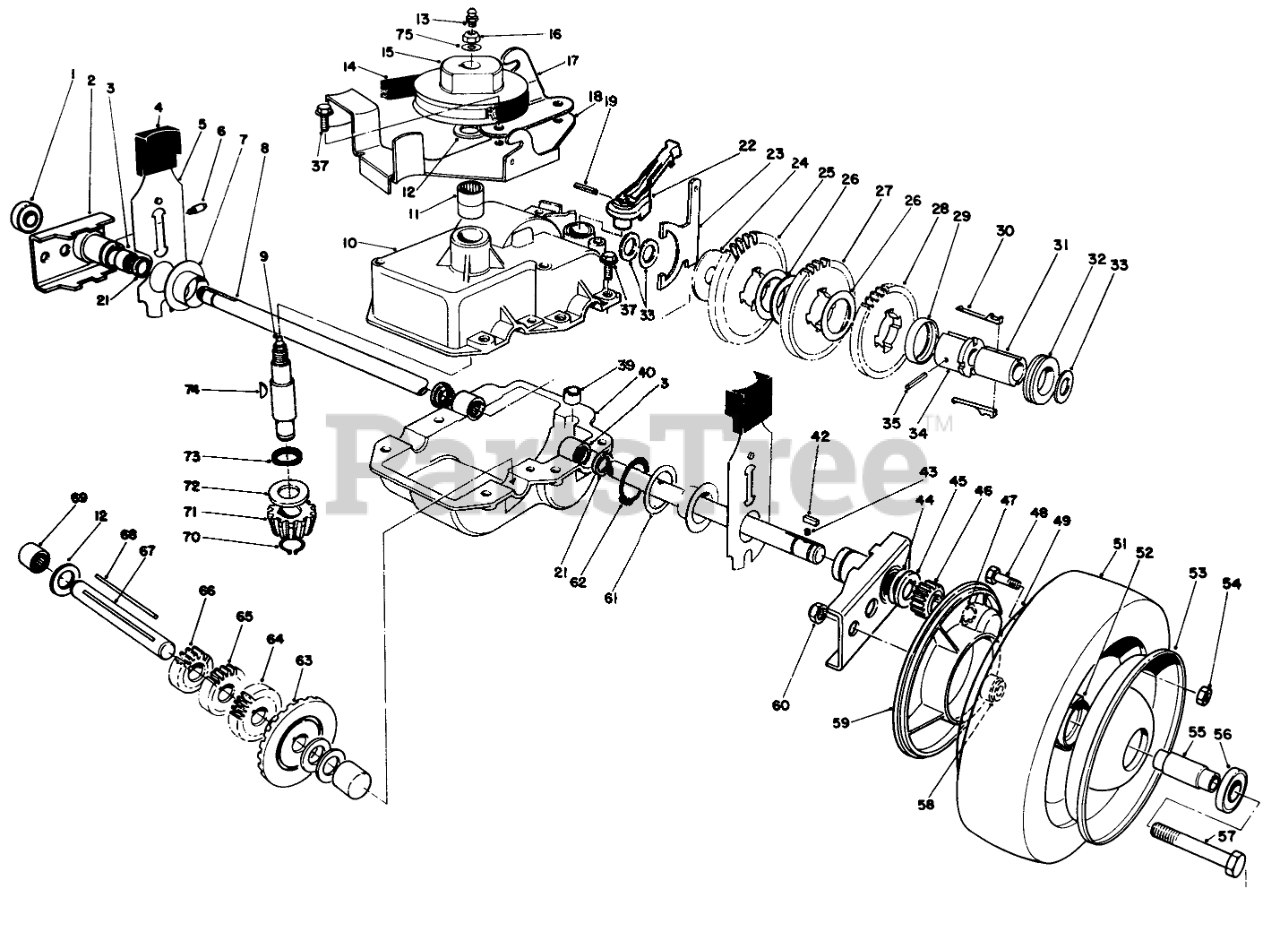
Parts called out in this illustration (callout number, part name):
1	BEARING-WHEEL
2	Pivot Arm Assembly (Incl. Ref. #1, 3, 6 & 21)
3	BEARING-ROLLER
4	KNOB-ARM
5	REAR SPRING ARM ASM
6	FITTING-GREASE
7	CAP-END
8	SHAFT-OUTPUT
9	Shaft-Input (Incl Ref. #13)
10	Upper Case Assembly (Incl. Ref. #11 & 73)
11	Bearing-Needle
12	WASHER-THRUST
13	FITTING-GREASE, ZERK
14	V-BELT
15	PULLEY
16	NUT-HEX
17	Bracket-Traction Engage
18	Belt Guide Bracket
19	PIN-COIL
21	SEAL-OIL
22	LEVER-SHIFT
23	YOKE-SHIFT
24	WASHER
26	WASHER
27	GEAR-42T
28	GEAR-38T
29	RETAINER-KEY
30	KEY-SHIFT
31	SLEEVE
32	COLLAR-SHIFT
33	WASHER-PLAIN
34	SLEEVE-GEAR
35	PIN-GROOVE
37	SCREW-HWHTF
39	BUSHING-YOKE
40	CASE-GEAR, LOWER
42	KEY RECTANGULAR
43	SPRING-COMPRESSION
44	WASHER-THRUST, OUTER
45	WASHER-THRUST, OUTER
46	GEAR-PINION
47	RING-RETAINING
48	SCREW-HH
49	Wheel-Half
52	HUB-BEARING
53	Wheel-Half
54	NUT-LOCK, NI
55	SPACER-BEARING
56	BEARING-WHEEL
57	SCREW-HH
58	SPACER-COVER, WHEEL
59	COVER-WHEEL
60	NUT-LOCK, CONE
61	WASHER
62	RING-RETAINING
63	GEAR-BEVEL
64	GEAR-18T
65	GEAR-14T
66	GEAR-12T
67	SHAFT-INTERMEDIATE
69	BEARING-NEEDLE, CLOSED
70	RING-RETAINING
71	PINION-BEVEL
72	WASHER-THRUST
74	KEY-WOODRUFF
75	WASHER-FLAT
